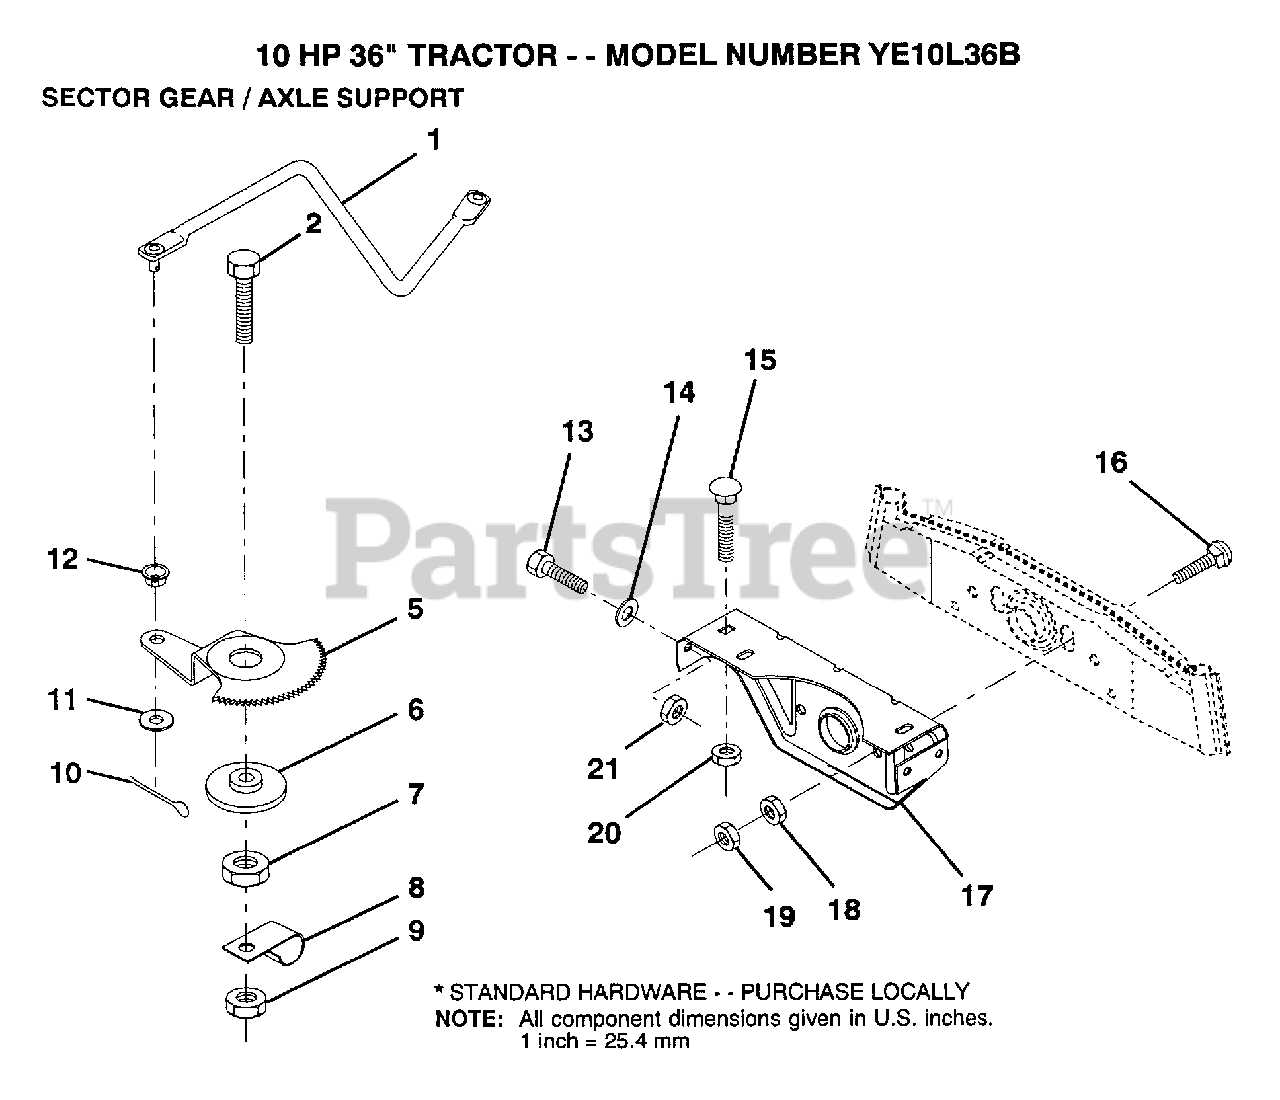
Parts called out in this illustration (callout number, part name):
1	DRAG LINK
2	"BOLT,HEX"
5	GEAR SECTOR
6	BUSHING
7	NUT
8	CLIP INSULATOR
9	NUT LTV
10	COTTER PIN
11	WASHER
12	BUSHING.DRAGLINK
13	BOLT
14	WASHER
15	BOLT
16	BOLT
17	"SUPT,FRT AXLE"
18	NUT.HEX.3/8-16UNC
19	LOCKNUT
